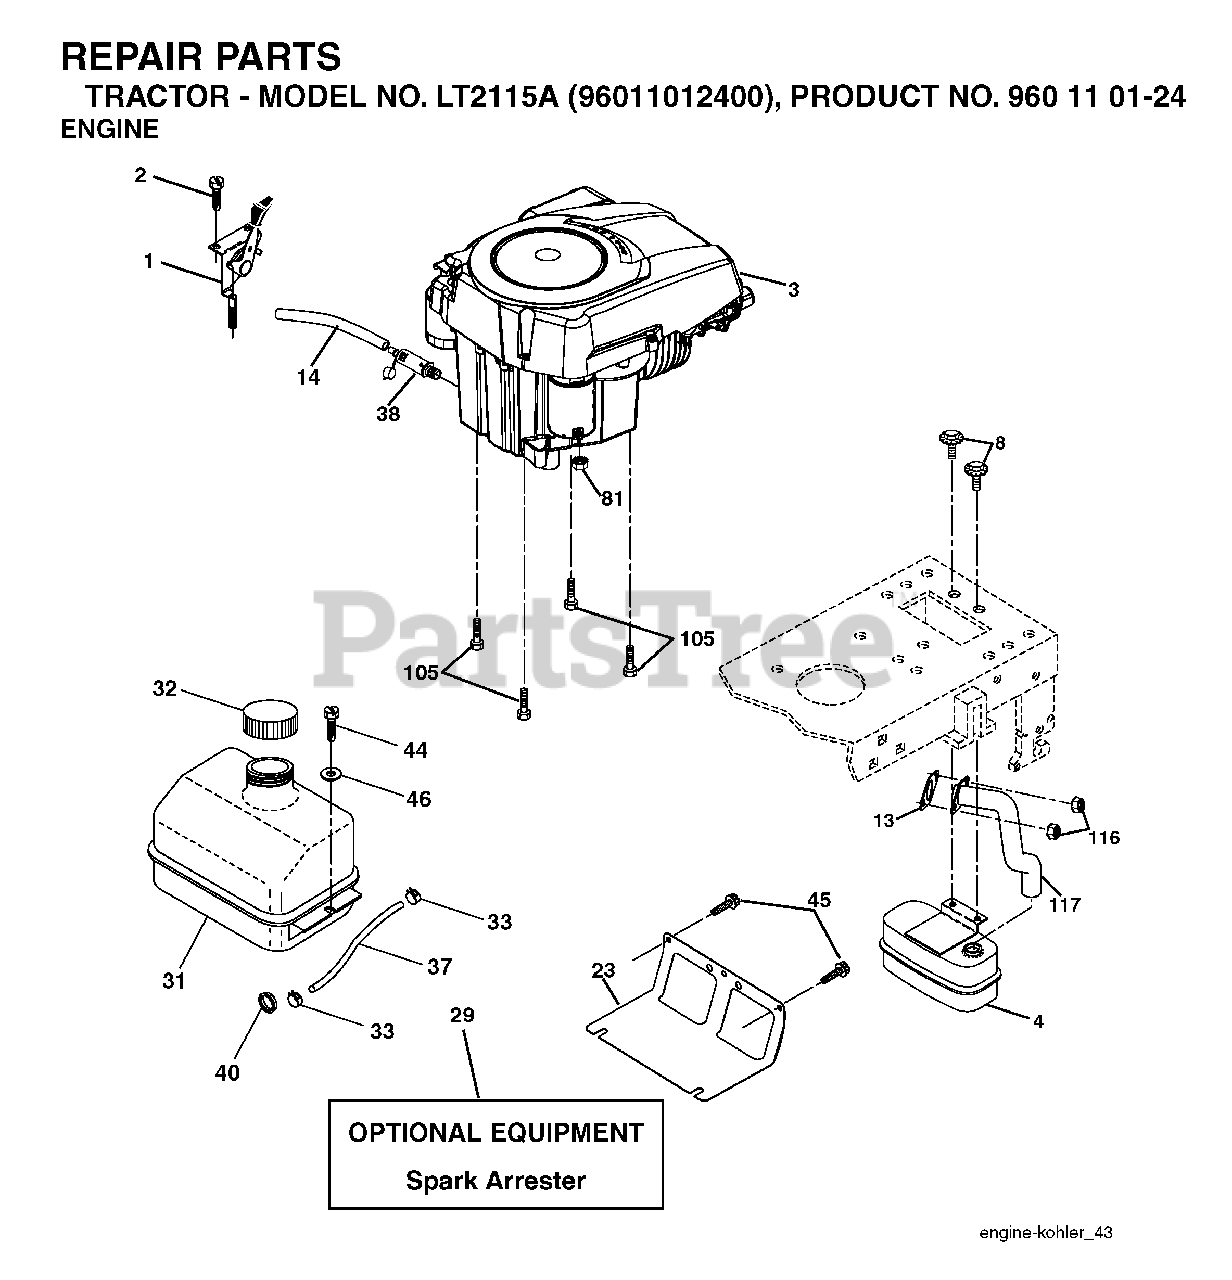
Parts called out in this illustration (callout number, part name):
1	CONTROL.THROTTLE.LT/YT
2	SCREW
4	MUFFLER.SINGLE.CYL.KOHL/B&S
8	BOLT, 5/16-18 X 1 3/4
13	GASKET ENGINE
14	TUBE, DRAIN OIL ASM.
23	SHEILD.BROWNING.DBR.GUARD
29	ARRESTER SPARK (OPTIONAL)
31	TANK FUEL FRONT
32	FUEL CAP
33	HOSE CLAMP
37	LINE.FUEL.20
38	PLUG DRAIN OIL EASY
40	GROMMET T
44	SCREW HEXWSHR 1/4-20X3/4
45	SCREW, 3/8-16X3/4
81	NUT
105	SCREW 3/8-16X1
116	NUT.HEX.FLANGE.TOPLOCK
117	TUBE EXHAUST
